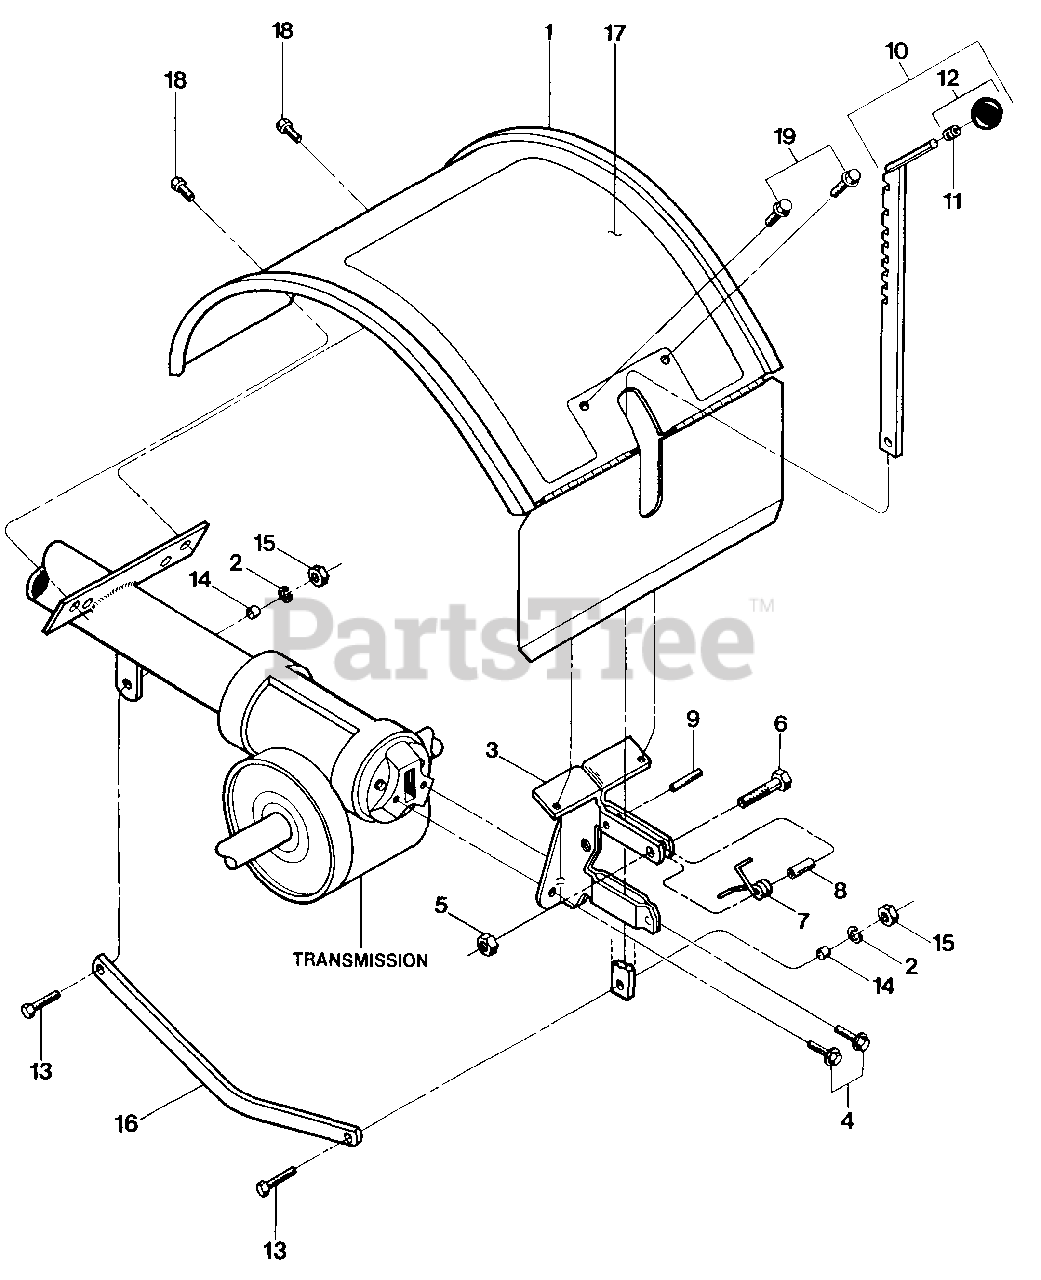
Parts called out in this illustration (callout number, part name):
1	Hood-tine cover, with hinged flap
2	Lockwasher-3/8
3	Bracket-hood & depth regulator
4	Screw-flanged hex hd., 5/16-18 x 5/8
5	Locknut-hex, 1/4-20
6	Screw-hex hd., 1/4-20 x 1
7	Spring-depth regulator plunger
9	Roll Pin-1/4 x 1
10	Bar Assembly-depth adjustment
11	Ring-retaining, tolerance ring
12	Knob-depth regulator
13	Screw-hex hd, 3/8-16 x 1-1/4
14	Bushing-spacer, drag bar
15	Nut-hex, 3/8-16
16	Drag Bar-depth regulator
17	Decal-tiller operating instructions
18	Screw-hex hd, self-tapping, 5/16-18 x 1/2
19	Screw-flanged hex hd, self-tapping, 1/4-20 x 1/2
